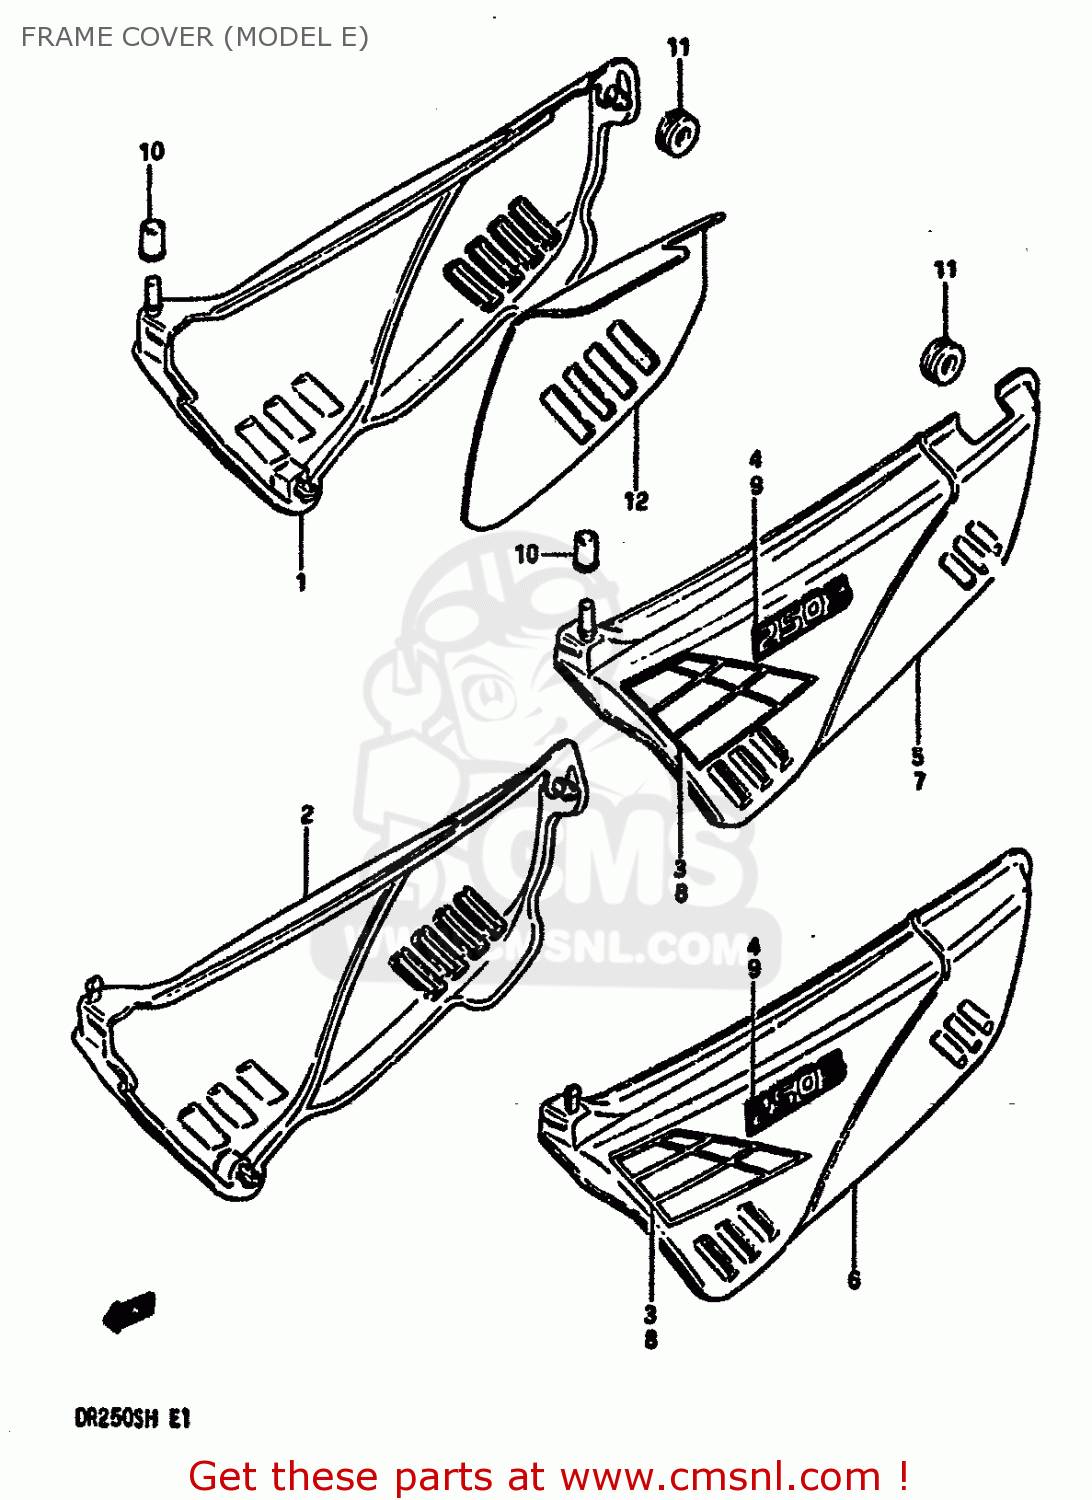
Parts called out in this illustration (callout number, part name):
1	COVER,FRAME RH
2	COVER,FRAME,RIGHT
3	TAPE SET, FRAME COVER RH
4	EMBLEM
5	COVER, FRAME, LH
6	COVER, FRAME, LH
7	COVER, FRAME, LH
8	TAPE SET, FRAME COVER LH
9	EMBLEM
10	CUSHION
11	CUSHION
12	HEAT SHIELD,FRAME COVER
